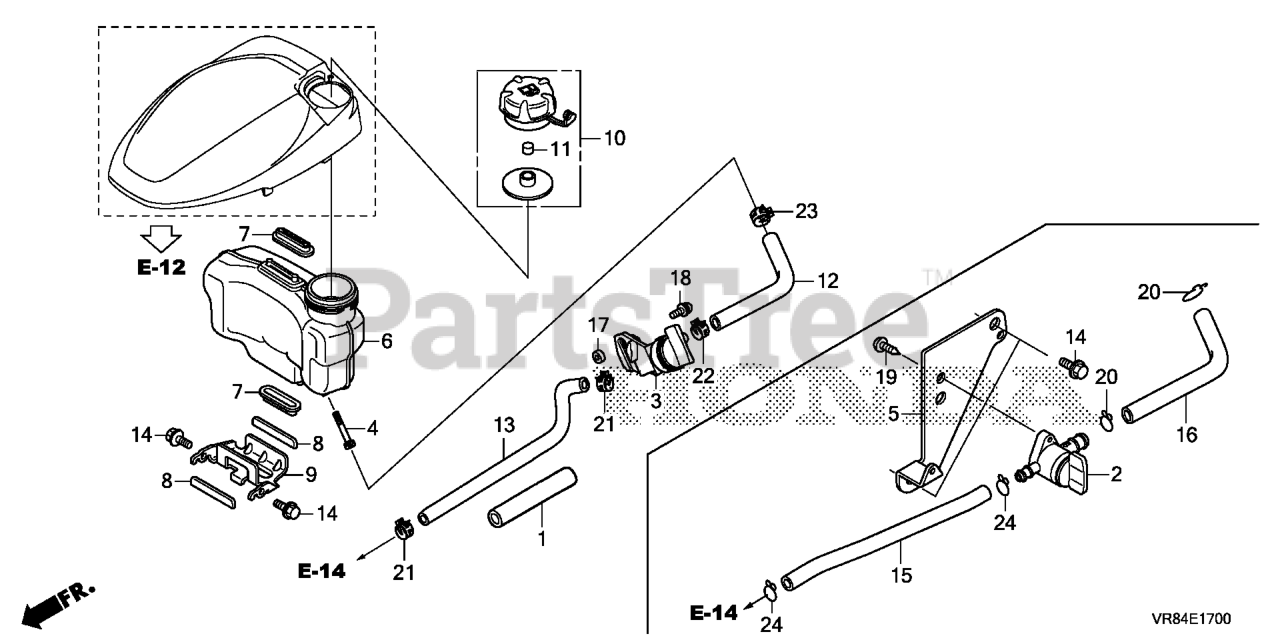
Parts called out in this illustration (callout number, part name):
1	RUBBER, SUPPORTER (107MM)
3	PETCOCK ASSY.
4	FILTER, FUEL
6	TANK, FUEL
7	RUBBER A, TANK MOUNTING
8	RUBBER B, TANK MOUNTING
9	STAY, FUEL TANK
10	CAP ASSY., FUEL TANK
11	SPONGE, FUEL CAP BREATHER
12	TUBE, FUEL TANK (FKM)
13	TUBE, FUEL (FKM)
14	BOLT, FLANGE (6X14)
17	COLLAR, FUEL PETCOCK
18	SCREW-WASHER (5X10)
21	CLIP, TUBE (D8)
22	CLAMP, TUBE (D10)
23	CLAMP, TUBE (D12)
